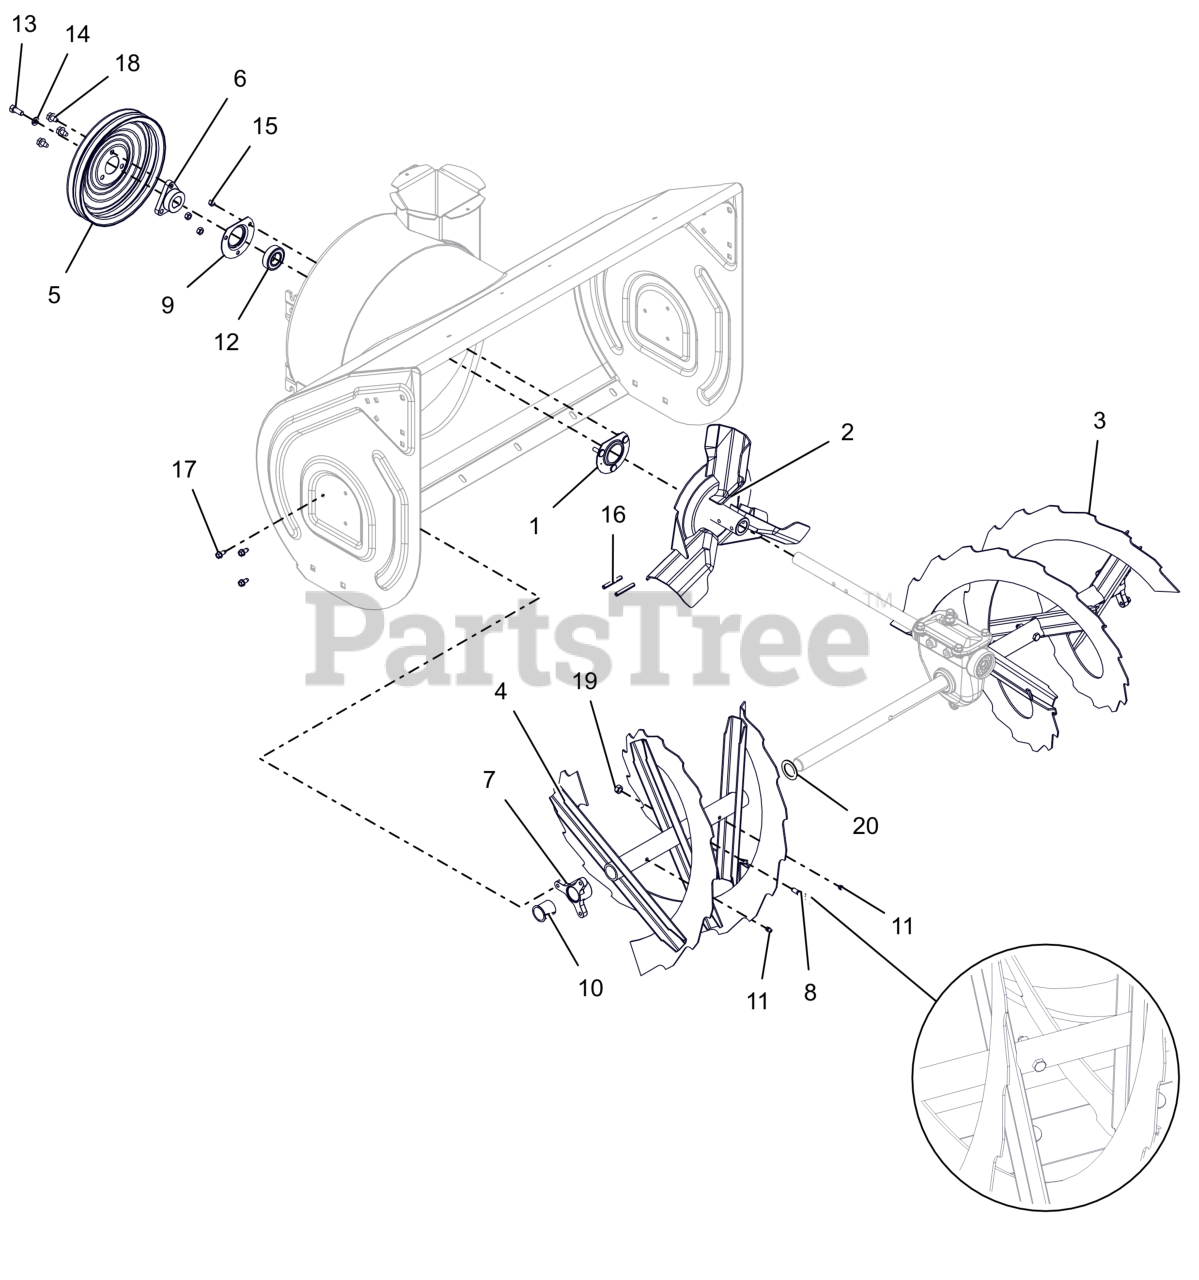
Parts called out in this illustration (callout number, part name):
1	BEARING FLANGE
2	IMPELLER, 3 BLADE-14"
3	RAKE, LH-32"(1 ID X 15.75 OD)
4	RAKE, RH-32"(1 ID X 15.75 OD)
5	PULLEY, SPIN FORM DUAL GROOVE
6	PULLEY HUB, D-BORE .87 PRO
7	BUSHING, RAKE SHAFT 1"
8	SHEAR BOLT SERVICE ASSEMBLY
9	BEARING FLANGE
10	BSHG-FLG SPLIT NYLINER 1.0" HP
11	ZERK,FITTING .25X.125 DRIVE IN
12	BRG-BALL .876X1.75X.50 RSTFP
13	BLT, HEX .31-24X.750 G5 ZCC
14	WSHR, LK-HVY .312X.097 ZCC
15	NUT,LK-CTR .25-20 GA ZCC
16	PIN-ROLL .250X1.75
17	SCR-TAP .25-20X.50 HWH ZCC
18	SCR,TAP .312-18X.50 HWH TR ZCC
19	NUT,LK-CTR .31-18 GA ZCC
20	WSHR, FLT 1.010X1.505X.062 ZCC
